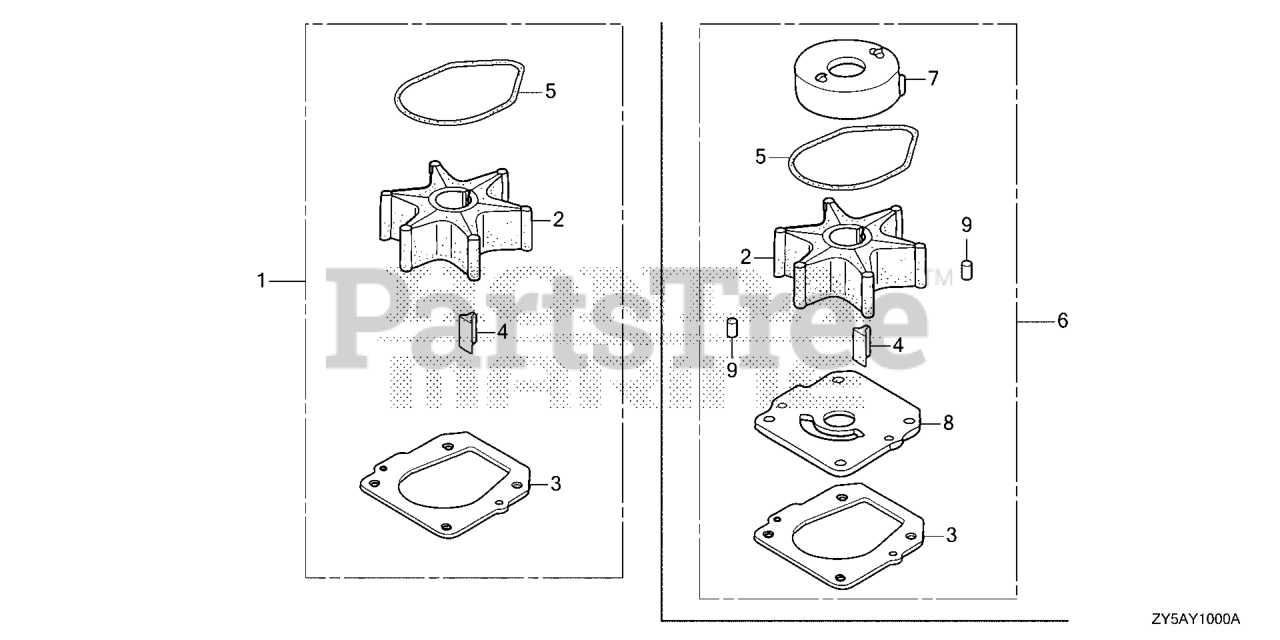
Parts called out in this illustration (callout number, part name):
1	PUMP KIT, IMPELLER
2	IMPELLER, PUMP
3	GASKET B, IMPELLER
4	KEY, WOODRUFF
5	O-RING, WATER PUMP
6	PUMP KIT, IMPELLER
7	LINER, PUMP
8	COVER, IMPELLER
9	PIN, DOWEL (6X10)
